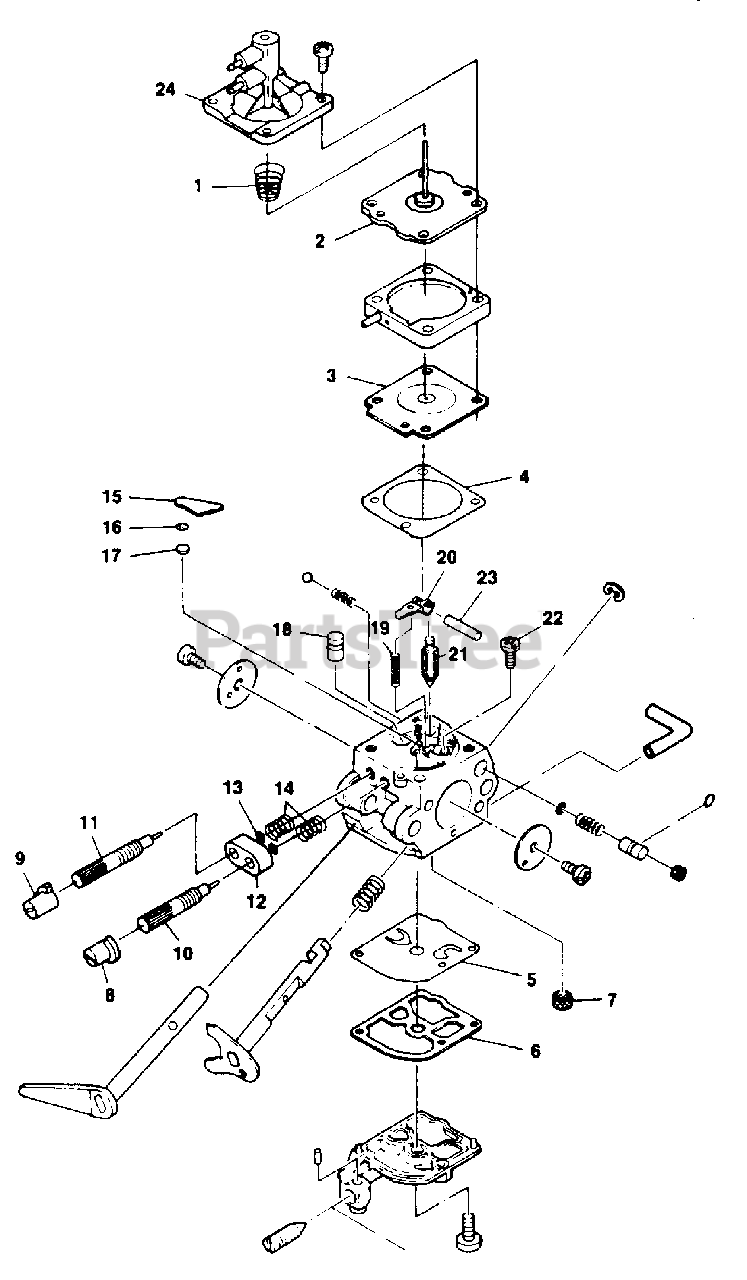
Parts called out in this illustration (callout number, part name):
1	Repair Kit
2	Repair Kit
3	Repair Kit
4	Repair Kit
5	Repair Kit
6	Repair Kit
7	Repair Kit
8	Repair Kit
9	Repair Kit
10	Repair Kit
11	Repair Kit
12	Repair Kit
13	Repair Kit
14	Repair Kit
15	Repair Kit
16	Repair Kit
17	Repair Kit
18	Repair Kit
19	Repair Kit
20	Repair Kit
21	Repair Kit
22	Repair Kit
23	Repair Kit
24	Oil Pump Body
